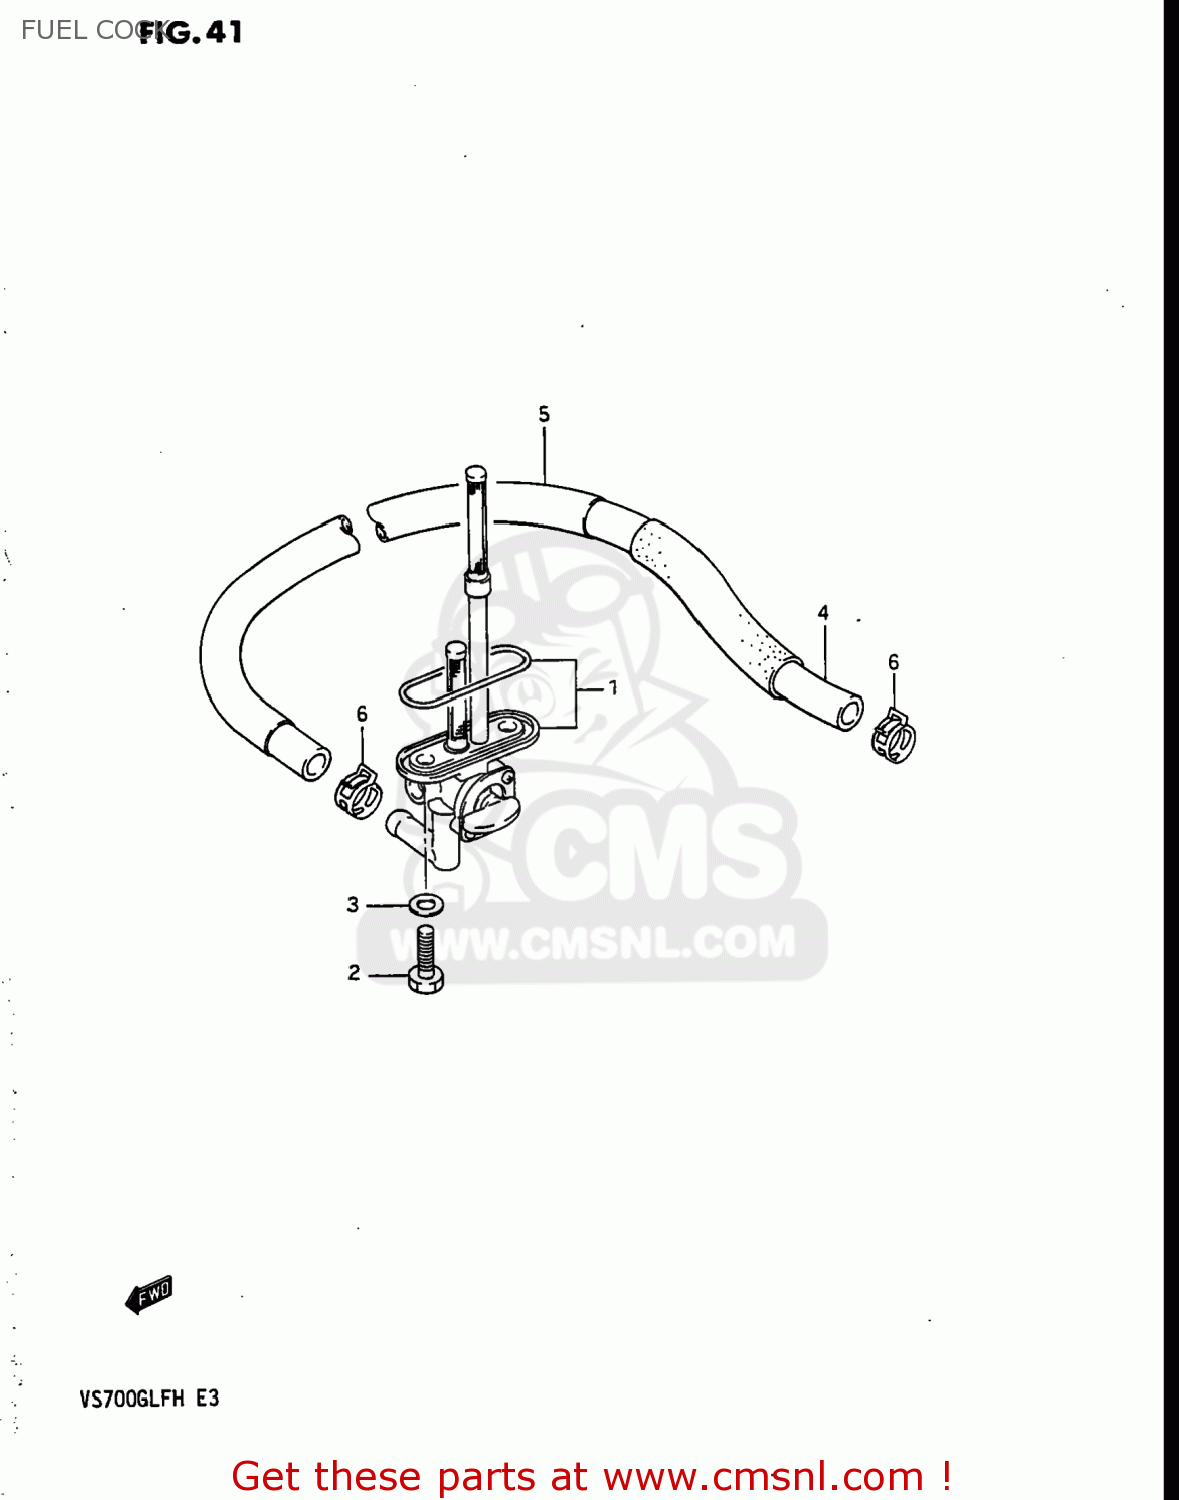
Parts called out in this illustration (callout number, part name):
1	COCK ASSEMBLY,FUEL
2	BOLT(6X20)
3	GASKET
4	HOSE,FUEL PUMP & COCK
5	TUBE,FUEL HOSE
6	CLAMP
